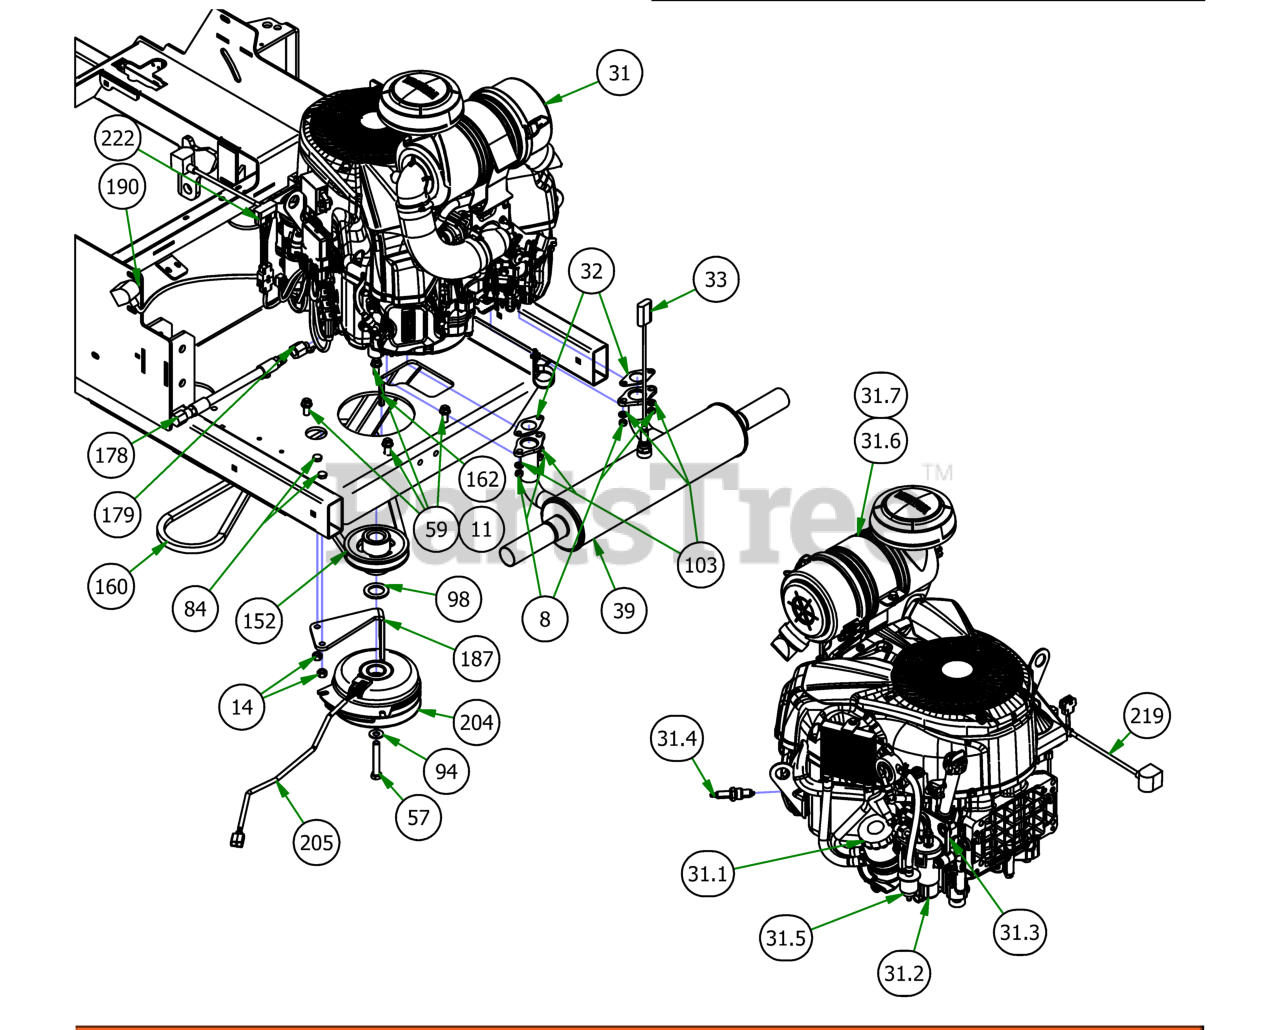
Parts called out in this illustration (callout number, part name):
8	M8-1.25 Zinc Nut
11	3/8-16 HEX SERRATED FLANGE NUT HARD/ZINC
14	3/8" Hex Nut
31	Yamaha 33hp EFI Engine
31.1	Oil Filter
31.2	Yamaha Fuel Pump
31.3	Yamaha Fuel Pump Bracket
31.4	Yamaha Spark Plug
31.5	Yamaha Fuel Filter
31.6	Canister Air Filter- Outer
31.7	Canister Air Filter- Inner
32	Exhaust Gasket for yamaha
33	O2 Sensor for Yamaha
39	Muffler for 27Hp Yamaha
49	M6-1.0 X 12MM DIN 933 HEX TAP BOLT (CL 8.8) ZINC
57	7/16-20 x 2 3/4 Hex C/S GR 8 Yellow Zinc
59	3/8 x 1 1/8 bolt
82	3/8 x 1 1/2 Bolt
84	3/8" x 1" Hex Bolt
94	3/8 FLAT WASHER USS (1" OD) ZINC
98	1 1/8" Flat Spacer
100	1/4 USS Flat Washer Zinc
103	5/16" Lock Washer
152	4 3/4 Motor Pulley
160	2019 Rogue Pump Belt 68"
162	1/4 x 2 Square key Stock
178	Oil drain Hose for Yamaha
179	Oil Drain Adapter for Yamaha
187	PTO Engager Holder
190	24" Red Battery Cable
204	Clutch Assembly
205	Clutch Pigtail
206	2019 Veritical Suspension Frame
208	Diesel Hydraulic Hose Clamp
219	Starter Cable
222	2019 Harness Adaptor - Vanguard 37 EFI Vert/Horiz
